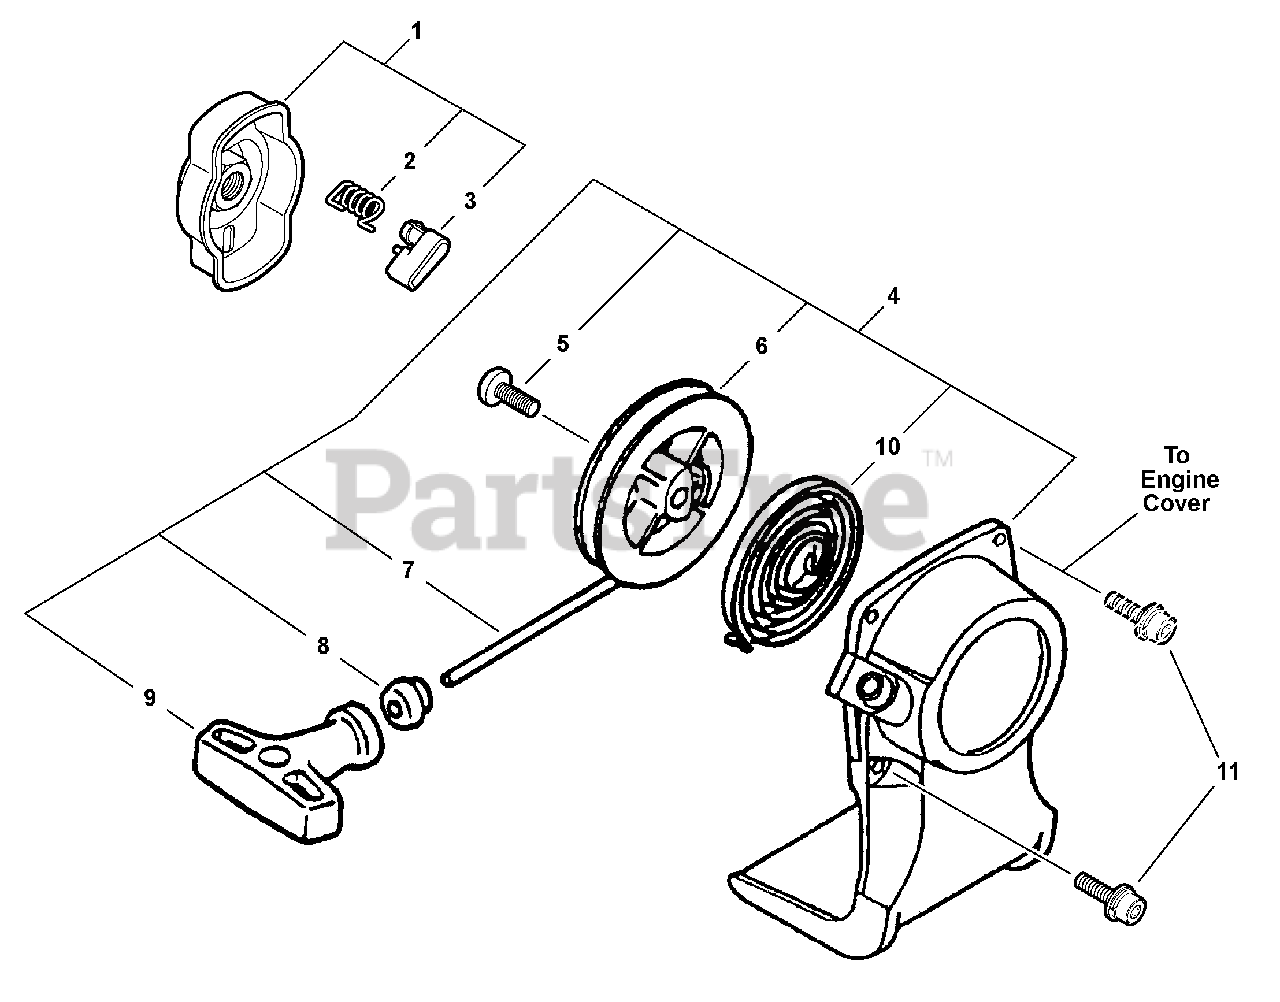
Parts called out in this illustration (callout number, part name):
1	Starter Pawl Asy
2	Spring, Return
3	Pawl, Starter
4	Starter Asy
6	Drum, Starter
7	Rope, Starter - 3x1000mm
8	Guide, Rope
9	Grip, Starter
10	Spring, Rewind
11	Screw 4x16
